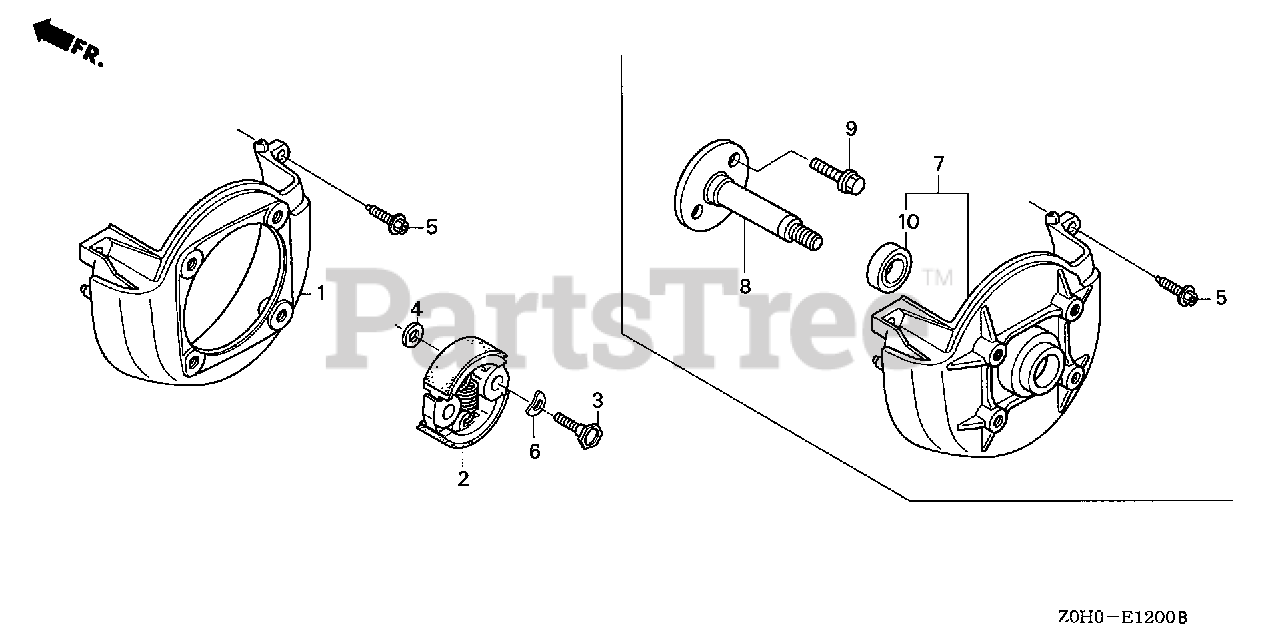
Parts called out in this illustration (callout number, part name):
1	COVER, FAN
2	CLUTCH ASSY.
3	BOLT, CLUTCH (6MM)
4	WASHER, CLUTCH (6X15)
5	BOLT, SOCKET (5X20)
6	WASHER, WAVE (8MM)
